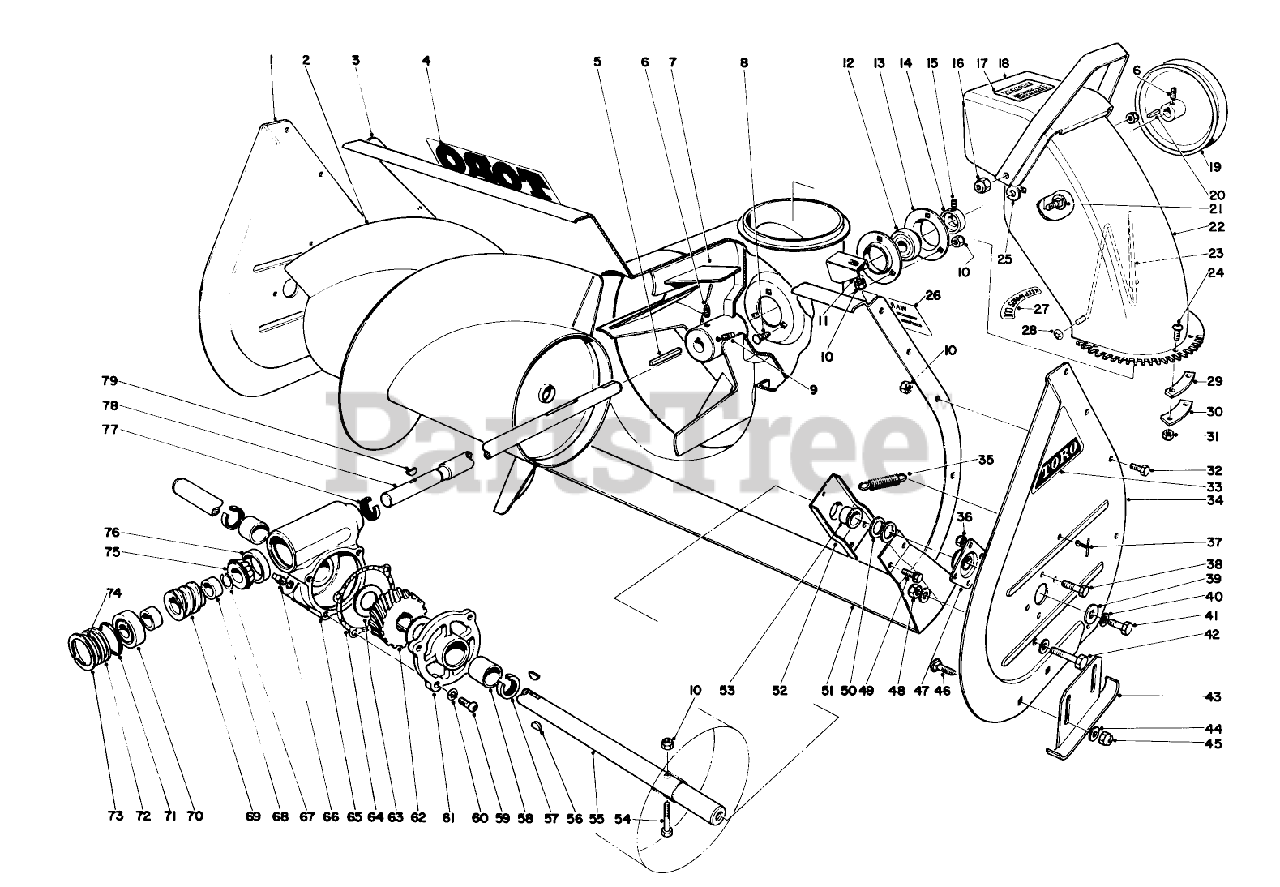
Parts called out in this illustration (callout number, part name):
1	Side Plate
2	Auger
3	Auger Housing
4	Decal
6	SCREW-SET, SQH
7	Impeller
8	BOLT-CARR
9	SCREW-SET, SQH
10	Nut
11	WASHER-LOCK
12	BALL BRG W/COLLAR
13	BRG FLANGE
14	EXT LOCKING COLLAR
15	SCREW-HSH
16	NUT-LOCK, NI
17	Decal
18	Deflector
19	1/2 X 9.5 DIA PULLEY
20	SQUARE KEY
21	SCREW-CARR
22	Upper Chute
23	WIRE-CHUTE
24	SCREW-HSBH
25	WASHER-FLAT
26	Decal
27	Decal
28	NUT-PUSH
29	CHUTE TAB SPACER
30	UPPER CHUTE TAB
31	Nut
32	SCREW-HH
33	Decal
34	Side Plate L. H.
35	SPRING-TENSION
36	NUT-LOCK
37	Retainer Spring
38	SCREW-HH
39	WASHER
40	WASHER-LOCK
41	SCREW-HH
42	SCREW-HH
43	Skid
44	WASHER-FLAT
45	NUT-LOCK, NI
46	BOLT-CARR
47	Bearing Flange
48	NUT-HEX
49	Hex Hd. Screw
50	Spacer
51	Scraper Blade
52	Mount Scraper (Incl. Ref. 53)
53	BUSHING-FLANGE
54	SCREW-HH
55	26 AUGER SHAFT
56	KEY-WOODRUFF
57	SEAL-OIL
58	Bushing
59	SCREW-HSFH
60	WASHER-LOCK
61	Cover Gear Box (Incl. Ref. 58)
62	GEAR-WORM, 27T
63	WASHER-THRUST
64	Gasket
65	Gear Box (Incl. Ref. 58 & 76)
66	PLUG-PIPE, SQH
67	RETAINER RING
68	Spacer
70	.750 BALL BEARING
71	O-RING
73	INTRNL RETAINING RING
75	3/4 ROLLER BRG CONE
76	1.750 ROLLER BRG CUP
77	SEAL-OIL
78	Shaft Worm
79	KEY-WOODRUFF
